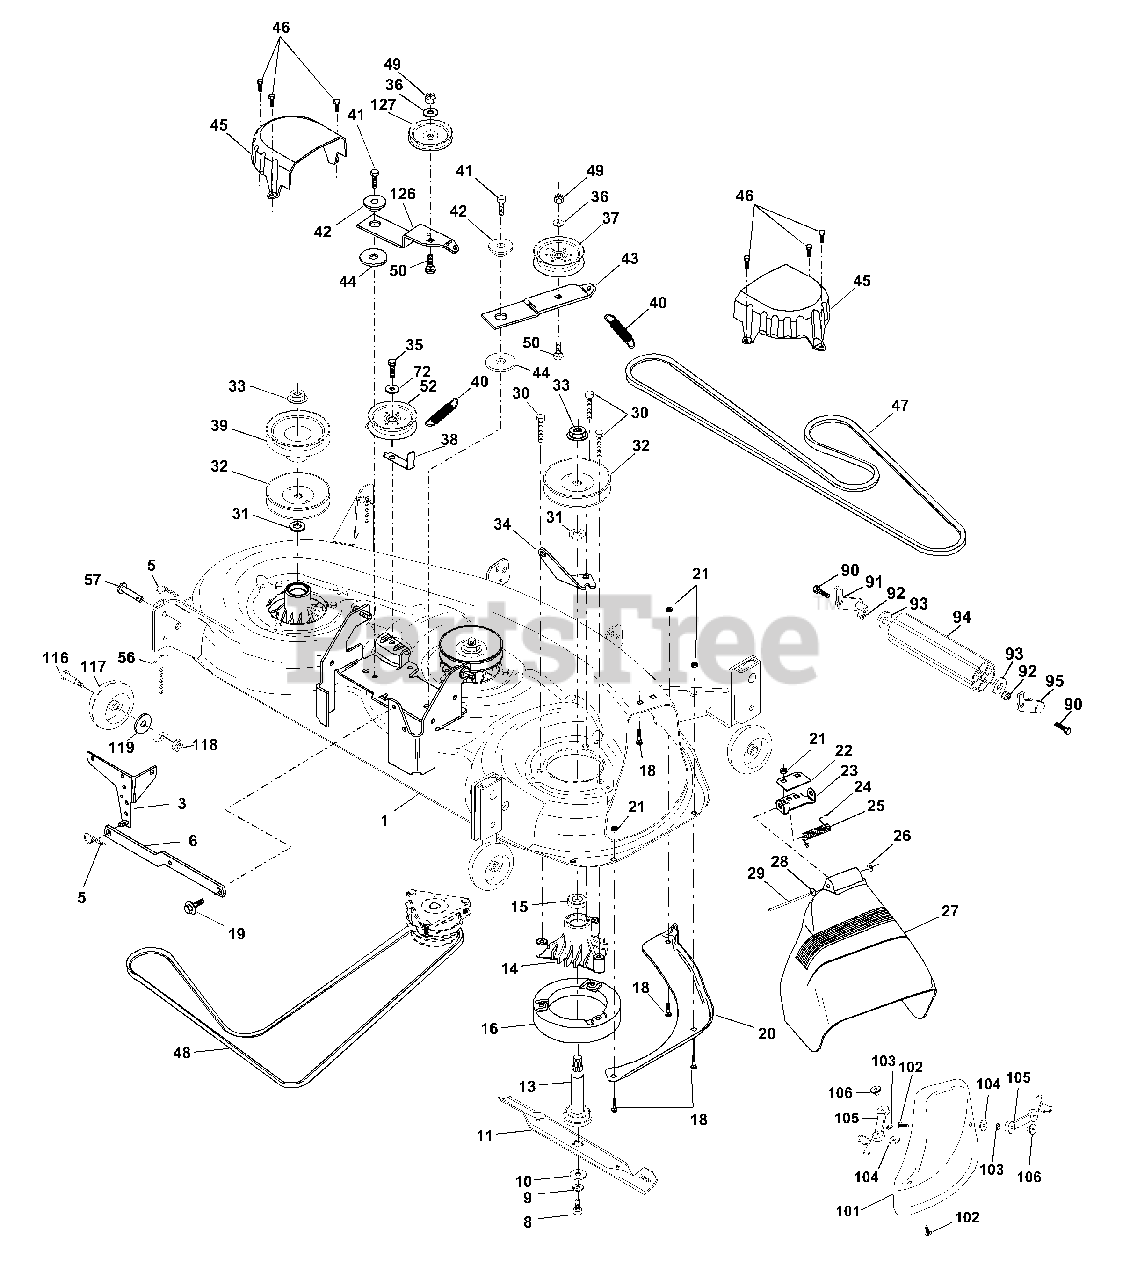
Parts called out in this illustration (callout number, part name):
1	Deck Weldment Mower HD 46 WAD
3	Bracket Asm., Sway Bar
5	Retainer Spring
6	Arm, Suspension, Rear (Sway Bar)
8	Bolt, Patched 3/8-24 x 1-1/4 Gr. 8
9	Washer, Lock Hvy., Unplated 3/8
10	Washer, Hard Blade, Mower Vented
11	Blade, 46" High Performance
11	Blade, 46" Mulching
13	Shaft Asm. w/Lower Bearing
14	Housing, Mandrel
15	Bearing, Ball, Mandrel
16	Stripper, Mower Round
18	Bolt, Carriage 5/16-18 x 5/8
19	Bolt, Hex Head, Shoulder 5/16-18
20	Baffle, Vortex Mower 46"
21	Nut, Crownlock 5/16-18 UNC
22	Stiffener, Bracket
23	Bracket, Deflector
24	Cap, Sleeve
25	Spring, Torsion, Deflector
27	Shield, Deflector Mower
28	Washer 11/32 x 5/8 x 16 Ga.
29	Rod, Hinge
30	Screw, Thdroll, Washer Head
31	Washer, Spacer Mower Vented
32	Pulley, Mandrel
33	Nut, Flg. Top Lock Cntr. 9/16
34	Anchor, Spring Deck 46"
35	Screw, Thdroll 3/8-16 x 1-3/4 Tytt
36	Washer 13/32 x 13/16 x 16 Ga.
37	Pulley, Idler, Flat
38	Keeper, Belt, Idler
39	Pulley, Idler, Driven
40	Spring, Secondary 44/46/50 Vent
41	Screw, Thdroll 3/8-16 x 1-1/4
42	Spacer, Retainer
43	Arm, Idler Secondary
44	Washer,Hardened
45	Cover, Mandrel Deck
46	Screw, Thdroll. 1/4-20 x 5/8
47	V-Belt, Mower, Secondary
48	V-Belt, Mower, Primary
49	Nut, Crownlock 3/8-16 UNC
50	Bolt, Carriage 3/8-16 x 1-1/2 Gr. 5
52	Pulley Idler Flat 46 Pri. Drive
56	Bar Pnt Adjusting Wheel Gauge
57	Pin Head Rivet
72	Washer 13/32 x 1 x 16 Ga.
90	Bolt, Fin, Hex 3/8-16 UNC x 1
91	Bracket, Asm Noseroller, LH
92	Nut, Lock, Hex w/Ins 3/8-16UNC
93	Washer 17/32 x 7/8 x 16 Ga.
94	Roller, Nose 38 & 42
95	Bracket, asm Noseroller RH
101	Cover, Mulching
102	Screw
103	Washer, Lock #10
105	Latch Asm. Bagger
106	Nut, Weld
116	Bolt, Shoulder
117	Gauge Wheel
118	Nut, Centerlock 3/8-16 UNC
119	Washer 3/8 x 7/8 x 14 Ga.
126	Arm, Idler, Primary Deck 46"
127	Pulley, Idler, V-Groove Dim. 4.25
